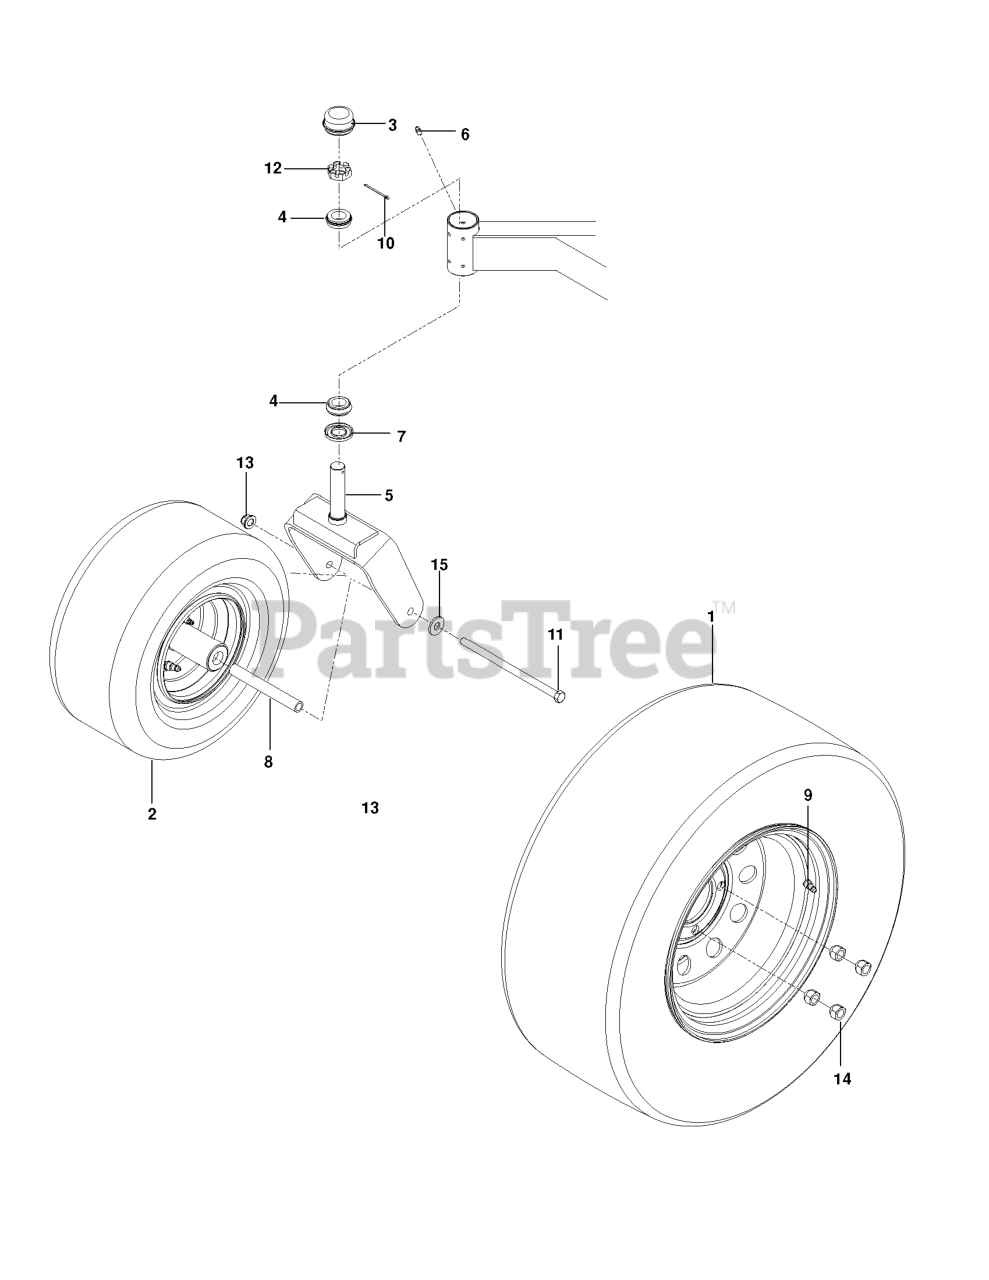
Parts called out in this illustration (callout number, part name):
1	WHEEL.ASSEM.22X10-10.SILVE.ZTR
2	TIRE.ASSEM.CASTER.13X6.5-6.SIL
3	GREASE CAP
4	TAPERED ROLLER BRG
5	YOKE.CASTER.ORANGE
6	ZERK
8	SPACER, PIVOT
9	VALVE STEM TR-412
10	COTTER PIN 1/8 X 2
11	HEX SCREW 1/2-13 X 9.5 GR5
12	NUT 1"C HEX SLOTTED
13	NUT, 1/2-13 HEX FLG NYLOC ZD
14	LUG NUT 1/2F
15	WASH USS FLAT 1/2
